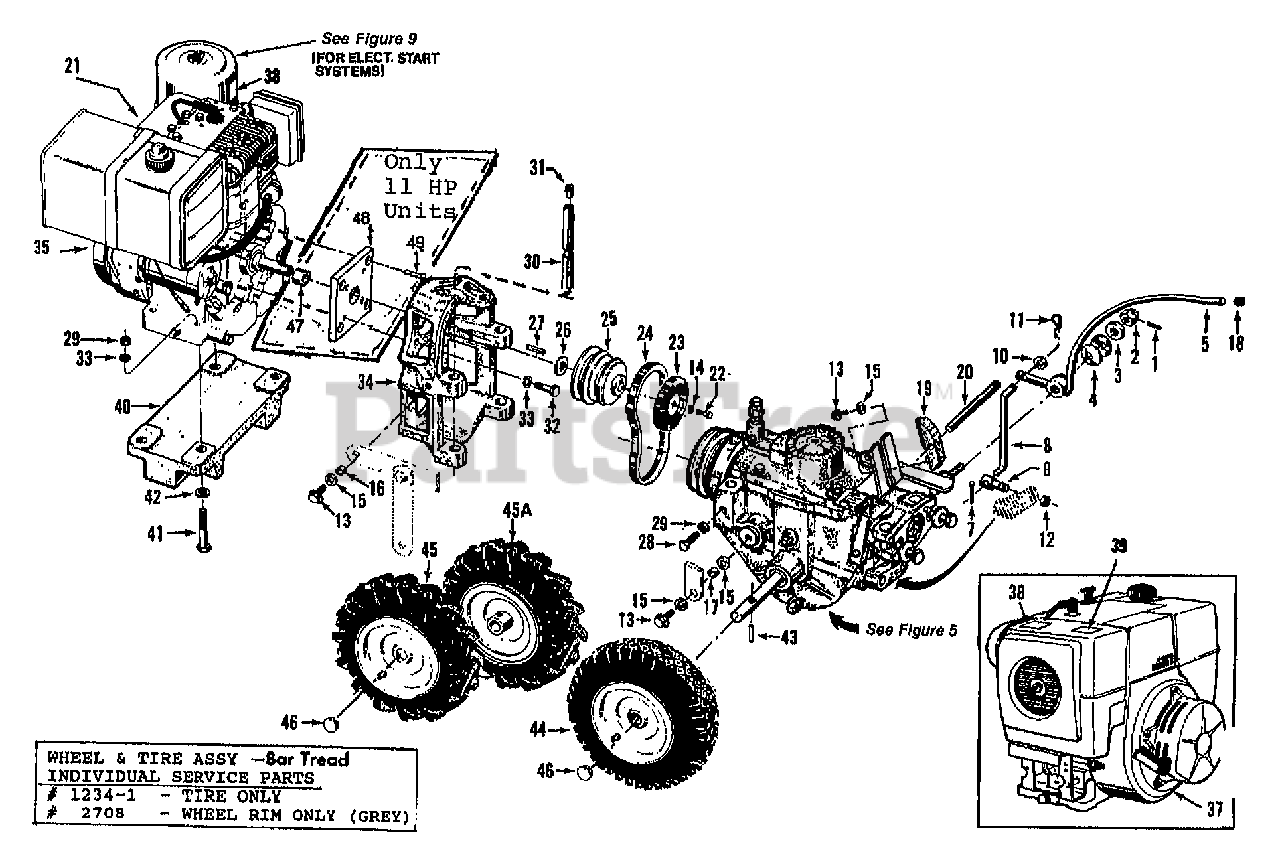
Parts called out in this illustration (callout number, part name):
1	PIN-SPRING .125 X 1
2	NUT-HEX 1/2-20
3	WASHER-# SHOULDER ZP
4	WASHER-# 1.97X1X.118
5	LVR-W/KNOB (WHEEL SPEED)
7	PIN-COTTER .094X1.0
8	ROD-CONNECTING
10	WASHER-FLAT 5/16 SAE
11	PIN-CLIP .08
12	NUT-H/LK 5/16-18
13	SCR-HFLK 3/8-16X1.00 ZP
14	WASHER-LK .375 @ DEPL
15	WASHER-FLAT 3/8 SAE
16	BUSHING-.5X.375X.325
17	BUSHING-.5X.375X.3
18	RING-TOLERANCE .5325 ID
19	KIT-ADJ BLOCK 4 SP
20	BAR-ADJUST
21	DECAL-STARTING STABIL
22	SCR-HH 3/8-24X1.5 G5
22	SCR-HH 3/8-24X1.75 ZP
23	KIT-ADJ BLOCK/REV DISC
23	DISC-REV
25	PULLEY-ENG MACH
25	PULLEY-ENG MACH U-HAUL
26	SHIM-1.0X.7656X.062
26	SHIM-1.0X.7656X.031
27	KEY-.188 SQ X 2.33
27	KEY-.25 SQ X 1.25
28	SCR-HH 5/16-18X1.0 G5 ZP
29	NUT-HEX 5/16-18 ZP
30	BAR-ENG MTG W/CAP PLUG
31	PLUG-CAP (RED)
32	BOLT-HH 5/16-24X1.125 G5 ZP
33	WASHER-LK .312 ZP
34	MOUNT-MOTOR HSE OPC PNT
35	7 HP BRIGGS & STRATTON ENGINE - RECOIL START
35	7 HP BRIGGS & STRATTON ENGINE - ELECTRIC START
35	8 HP BRIGGS & STRATTON ENGINE - RECOIL START
35	8 HP BRIGGS & STRATTON ENGINE - ELECTRIC START
35	8 HP KOHLER MAGNUM ENGINE - RECOIL START
35	8 HP KOHLER MAGNUM ENGINE - ELECTRIC START
35	11 HP BRIGGS & STRATTON ENGINE - RECOIL START
35	11 HP BRIGGS & STRATTON ENGINE - ELECTRIC START
38	DECAL-HOT SURFACE
39	DECAL-STABIL STARTING
40	WEIGHT-ENG ECONO PNT
41	SCR-HH 5/16-18X2.25 G5ZP
42	SPACER-.88X.385X.09 ZP
43	PIN-SPIROL .313 X 1.5
44	ASSM-STD TIRE
45	TIRE-LT BT GARDEN TRAC
45A	TIRE-RT BT GARDEN TRAC
46	CAP-HUB BLK PLASTIC
47	SPACER-1.25X1.001X.75
48	PLATE-ADAPTER 11HP PNT
49	SCR-FLHH 5/16-24 X .75 ZP
